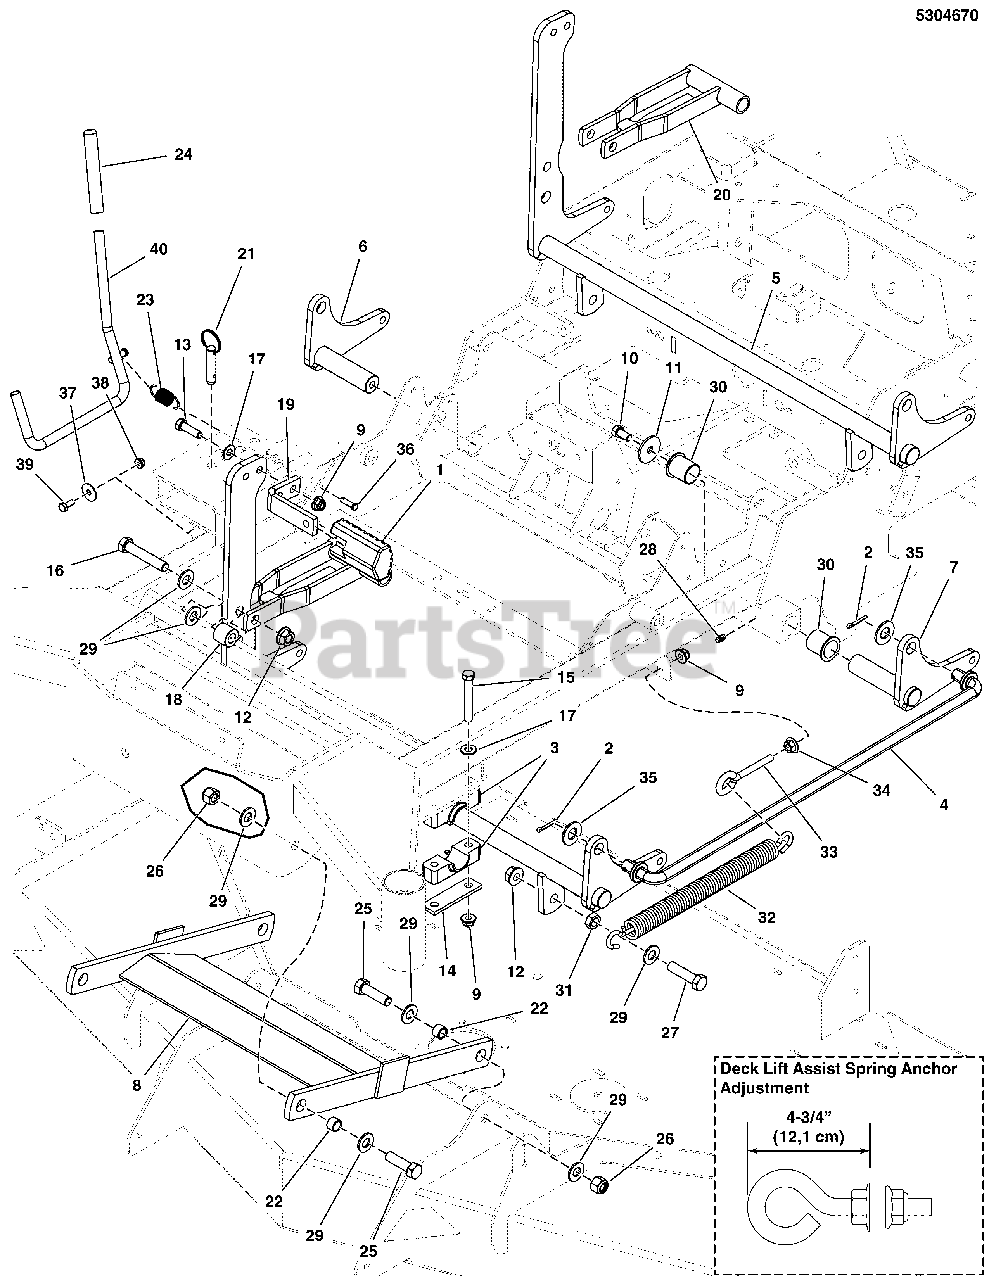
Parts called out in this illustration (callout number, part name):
1	PEDAL, Rubber
2	PIN, COTTER, 1/8 X 1-1/4
3	PIVOT BLOCK, PLASTIC
4	ROD, DECK LIFT, 560Z
5	WELD, DECK LIFT SHAFT, 560Z - BLK
6	WELD, DECK LIFT PIVOT, RH - BLK
7	WELD, DECK LIFT PIVOT, LH - BLK
8	WELD, PULLER BAR, 125 FRAME - BLK
9	NUT, Hex Flange, Nylock, 3/8-16
10	BOLT, 3/8-16 X 3/4, PLT W/PATCH
11	WASHER, .390 X 1.50 X .109, CZ
12	NUT, 1/2-13 HEX NYLOCK FLANGE
13	BOLT, 3/8-16 X 1-1/4 GD5 CZ
14	PLATE, Pivot
15	BOLT, 3/8-16 X 2-3/4 GD5 CZ
16	BOLT, 1/2-13 X 2-3/4 GD5 CZ
17	WASHER, .406
18	SPACER, .52 X 1.00 X .88, PM, CZ
19	PEDAL, FOOT - BLK
20	WELD, DECK HEIGHT LINK, IS700 - BLACK
21	PIN, HITCH, 1/2 X 2.00 OAL, CZ
22	INSERT, BEARING
23	SPRING-EXT, .740 ODX2.025LGX.072WR, BLK
24	GRIP, FOAM, .475 X 4.35 X .095
25	BOLT, 1/2-20 X 1-3/4 GD8 CZ
26	NUT, 1/2-20 HEX NYLON LOCK
27	BOLT, 1/2-13 X 2 GD5 CZ
28	GREASE FITTING, 1/4-28 STRAIGHT
29	WASHER, 1/2 SAE
30	BUSHING, 1.00 X 1.13 X 1.38, PLASTIC
31	NUT, 1/2-13 HEX JAM
32	SPRING-EXT, 1.00 ODX13.25LGX.177WR, BLK
33	EYE BOLT, 3/8-16 X 6, 3THRD, 1EYE, CZ
34	NUT, 3/8-16 HEX SERRATED FLANGE
35	WASHER, Blade Bolt, 9/16"
36	PIN, CLEVIS, 1/4 X 1/2, PLATED
37	WASHER, 1/4 FENDER
38	NUT, Flange Nylock , 1/4-20
39	BOLT,1/4-20X5/8
40	WELD, Rod, Deck Lift - BLK
